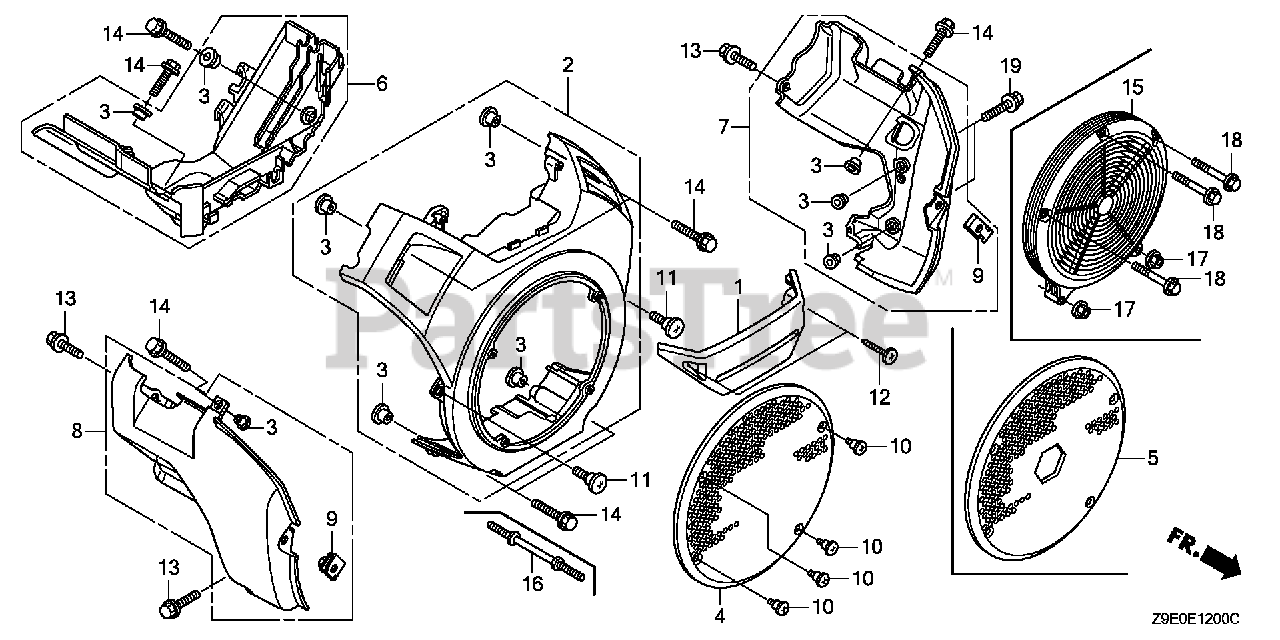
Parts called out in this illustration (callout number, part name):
1	COVER, FUEL PUMP
2	COVER, FAN *R280* (POWER RED)
2	COVER, FAN *NH1* (BLACK)
3	COLLAR, FAN COVER
5	PROTECTOR, FAN COVER (P.T.O.)
6	SHROUD (UPPER)
7	SHROUD, R. (LOWER)
8	SHROUD, L. (LOWER)
9	NUT, FENDER SETTING
10	SCREW, SPECIAL (4X10)
11	SCREW, SPECIAL (6X15)
12	SCREW, TAPPING (5X20)
13	BOLT, FLANGE (6X16) Use from Engine SN 2056820.
14	BOLT, FLANGE (6X20)
19	BOLT, FLANGE (6X20)
